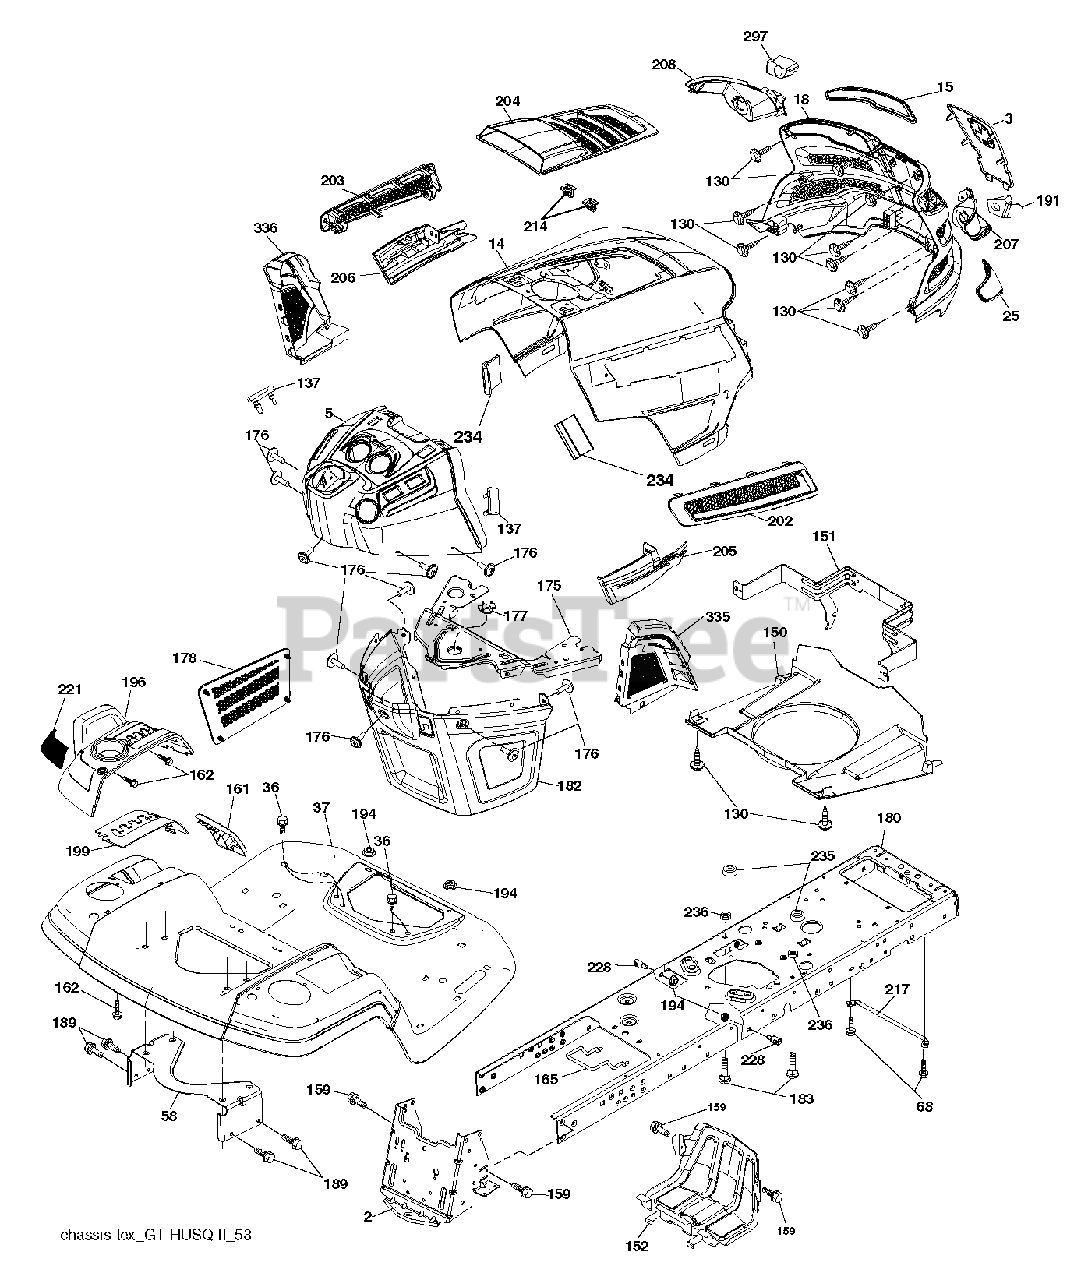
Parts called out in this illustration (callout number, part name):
2	DRAWBAR.STGT
3	APPLIQUE.SUBASM.GT.HUSQ.II
5	DASH.UPP.GT2.DUAL.RD.PTO.MCHOK
14	HOOD.ASM.HUSQVARNA.GT.TEX.422
15	LENS.HEADLIGHT.LH.GTII.2011
18	GRILLE.SUBASM.GT.HUSQ.II
25	LENS.HEADLIGHT.RH.GTII.2011
36	SCREW 5/16"
37	FENDER.PNT.TX.GT.CH/FW/DL.HUSQ
58	BRKT.SUPPORT.FNDR/TANK
68	SCREW LT
130	SCREW.#10 X 0.750.BOS
137	BUMPER DASH
150	AIR.DUCT.GTV.BLACK
151	BRACKET.PIVOT.HOOD.GT.HUSQ.II
152	SHIELD.BROWNING.PNT.GT.V2
159	SCREW, 3/8-16X3/4
161	CONSOLE.WINDOW.FUEL.HUSQ.GT
162	SCREW.HI-LO.CONSOLE
165	SUPPORT.TANK.REAR.B/TE
175	PLATE.CROSSMEMBER.HUSQ
176	SCREW.#10-24X5/8.RN.QU
177	BUSHING, STEERING
178	CARGO.ASM.NET.TXGT.W/C
180	CHASSIS.STAMPING.LT/GT
182	DASH.LOWER.COMMON.12V.ADAPTOR
183	BOLT.5/16-18X1-1/4 FULL THD
189	SCREW
191	INSERT.REFLECTIVE.RH.HUSQ.GTII
194	NUT LOCK HEX FLANGE 5/16-18
196	CONSOLE.ASM.DECKLIFT.HUSQGT.DL
199	PLATE.DECK.LIFT.HUSQVARNA.GT
202	VENT.SIDE.RH.GT.HUSQ.II.
203	VENT.SIDE.LH.GT.HUSQ.II.498
204	VENT.TOP.HUSQ.GT2
205	SIDE.TRIM.RH.GT.HUSQ.II
206	SIDE.TRIM.LH.GT.HUSQ.II.GRAY
207	BEZEL LIGHT.RH.GT.II.MYLAR
208	BEZEL LIGHT.LH.GT.II.MYLAR
214	CLIP.RETAINER.TINNER.
217	ROD.PIVOT.HOOD
221	REFLECTOR.LH.TEX GT HU
228	STUD.FASTNER.W/ANTI-ROTATE
234	BUMPER.HOOD.TEX.HUSQVARNA
235	SPACER FENDER
236	NUT.CENTERLOCK.5/16-
297	INSERT.REFLECTIVE.LH.HUSQ.GTII
335	COVER.RH.CLOSE.OUT.BLACK
336	COVER.LH.CLOSE.OUT
